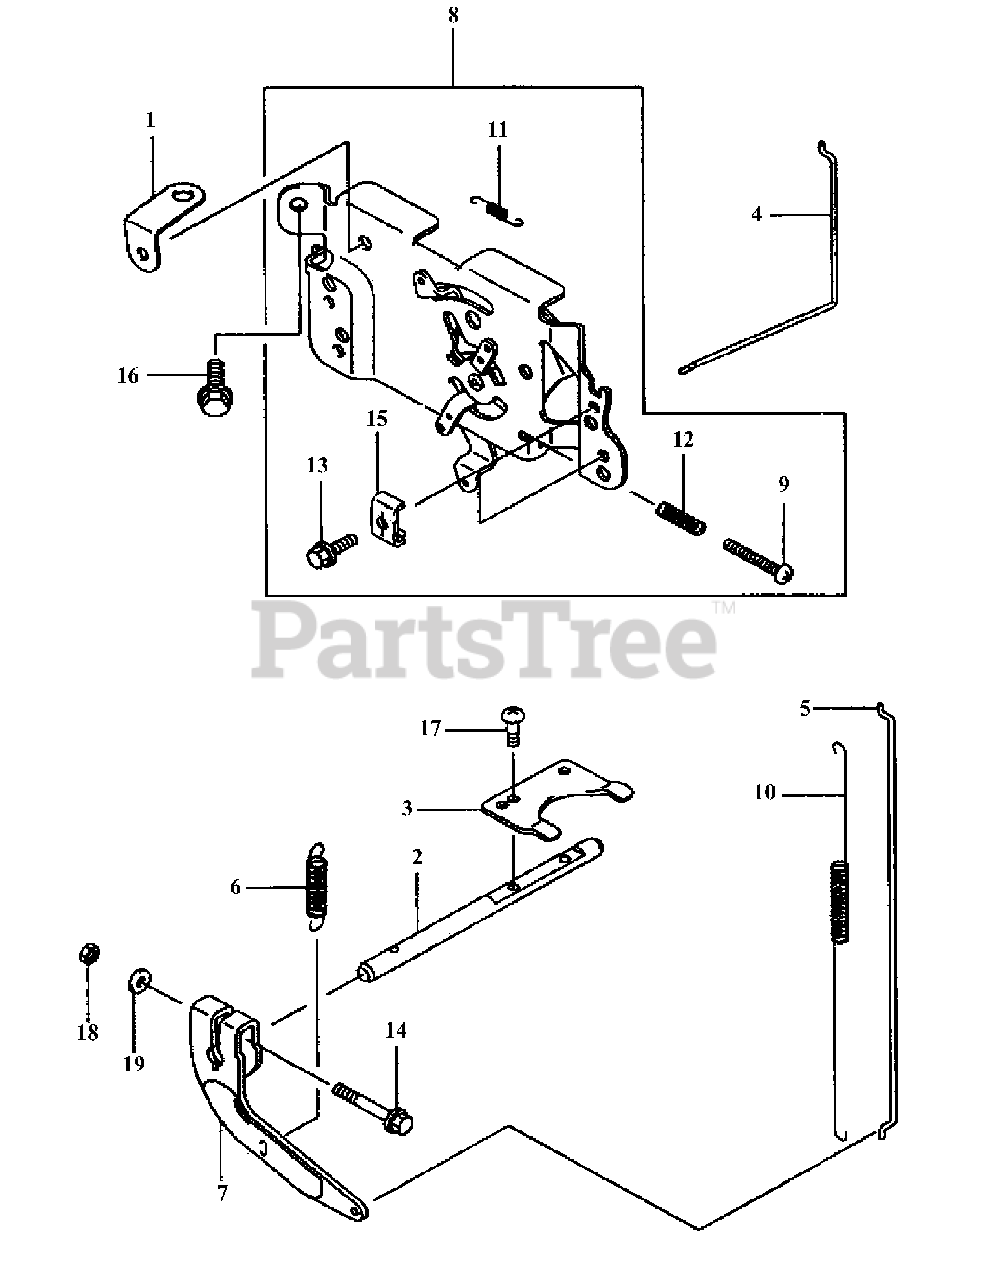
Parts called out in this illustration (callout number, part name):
6	Spring, Governor
7	Arm, Governor
8	Panel, Complete Control
11	Spring
16	Bolt, Flanged
19	Washer, Plain
